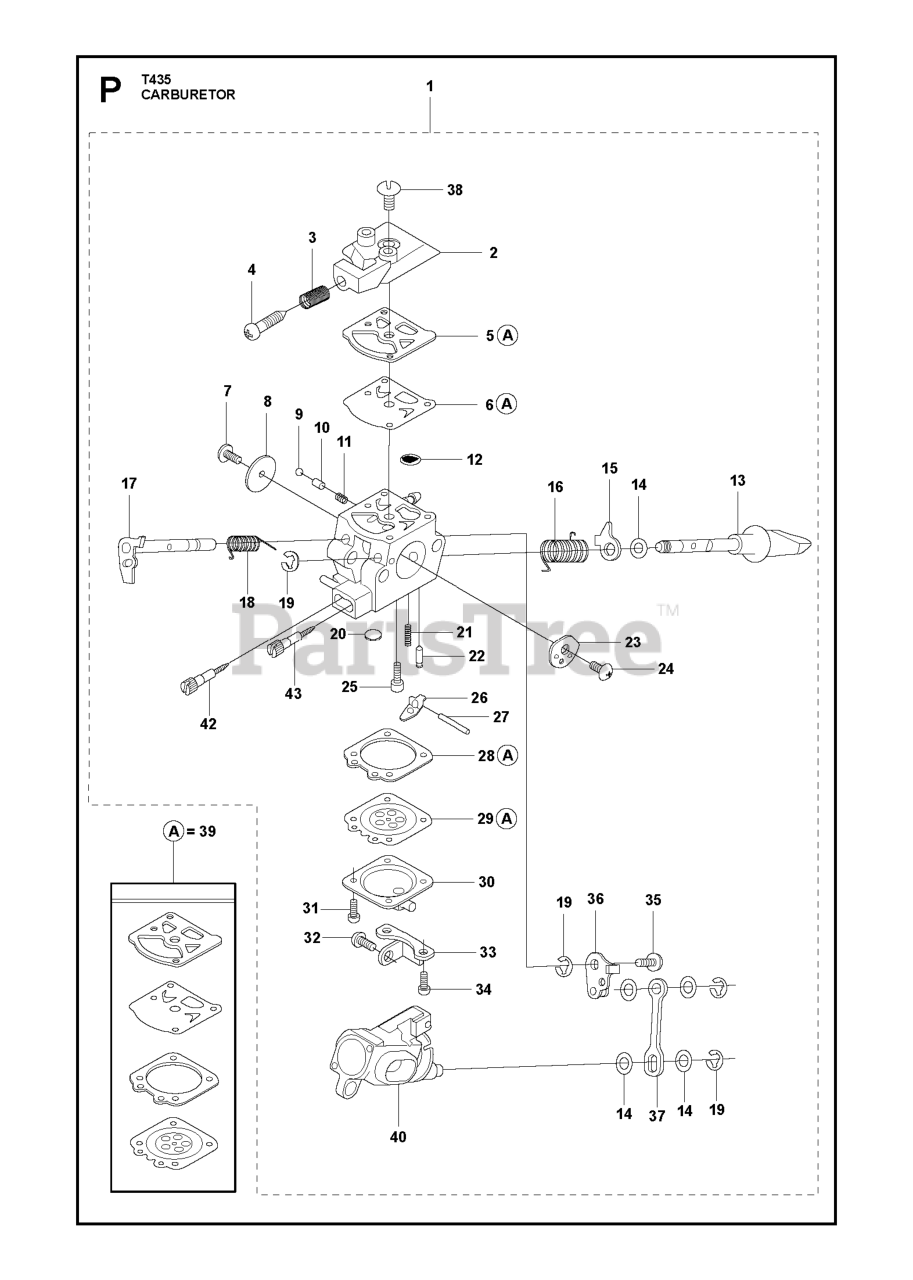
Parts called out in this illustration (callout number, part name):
9	BALL
10	PISTON
12	SCREEN
17	SHAFT ASST THRO
18	SPRING RETURN
22	VALVE INLET
23	CHOKE VALVE
31	SCREW ASSY
33	BRACKET 167-596
34	SCREW ASSY
36	LINK ASSY THROT
39	GASKET, KIT
40	BODY ASSY AIR VALVE 5-8416
